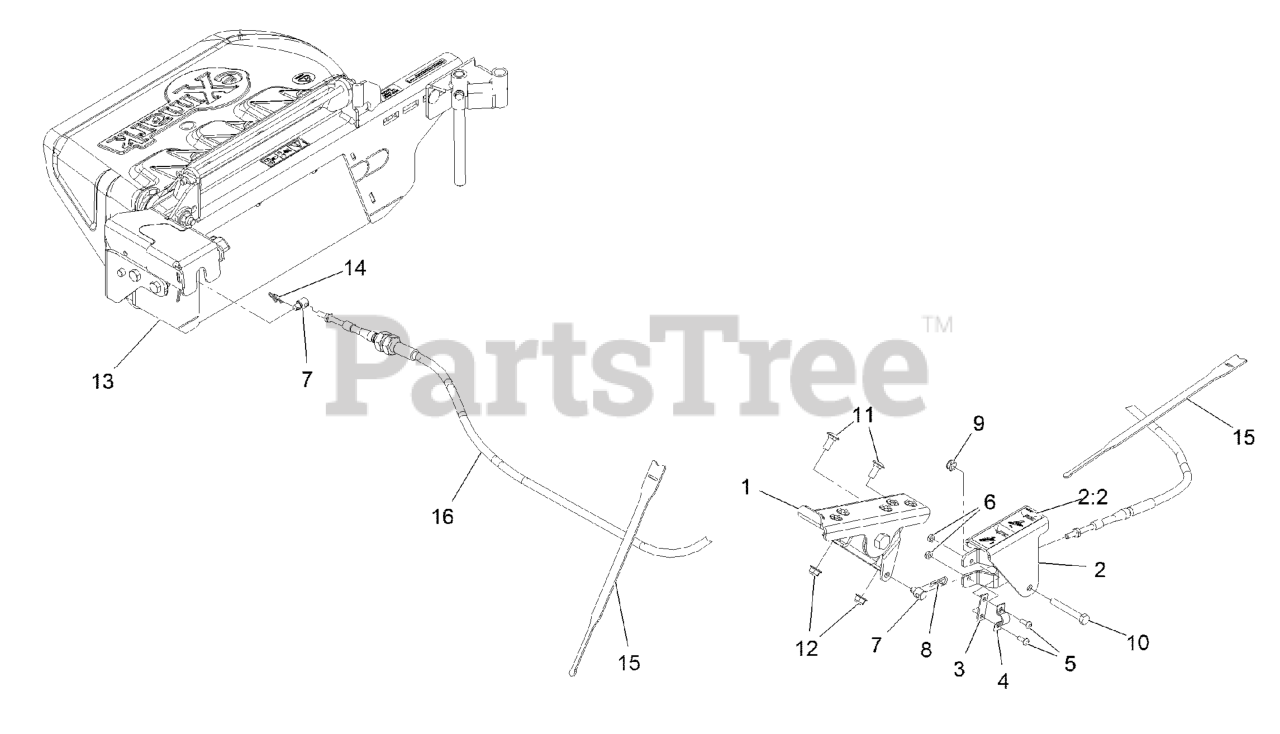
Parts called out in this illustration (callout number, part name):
1	ASM, PEDAL, OCD GATE
2	ASSEMBLY, CABLE BRACKET
2:2	DECAL-OCD OPERATION
3	SHIM,CONTROL CABLE
5	SCREW-HSBH
6	NUT-LOCK, NI
7	PIVOT, CONTROL CABLE
8	PIN-COTTER
9	NUT-LOCK, NI
10	SCREW-HH
11	SCREW-CARR
12	NUT-HF, NI
13	ASM, OCD
14	PIN-COTTER, LOCKING
15	STRAP-VELCRO, CABLE TIE
16	CABLE-DISCHARGE GATE
